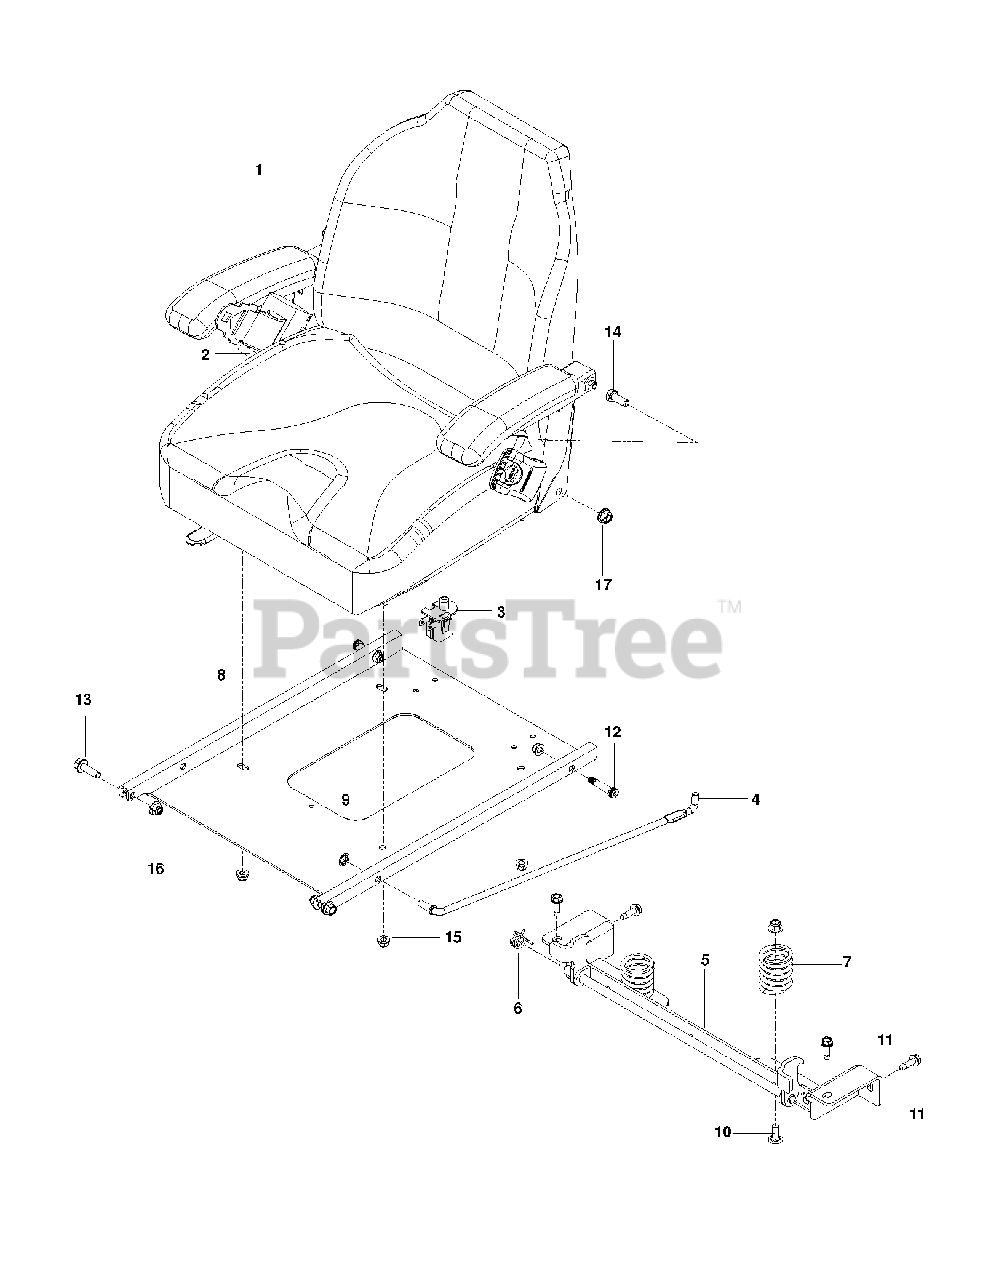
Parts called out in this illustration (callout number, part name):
1	SEAT.907.VINYL.HUSQVARNA
2	BELT, SEAT
3	SEAT SWITCH
5	LATCH.SEAT.BLACK
6	SPRING, TORSION
7	SPRING, SEAT
8	PAN, SEAT, BLACK
9	NUT 3/8 PALNUT RTNG BLK PHOS
10	RHSNB 3/8C X 1
11	RP BLT 5/16-18 X 1 THRD FORM D
12	BOLT, SHOULDER 3/8 X 1.25
13	HHFS 3/8-16 X 1.25 GD 5
14	HCS 7/16-14 X 1 GR 5 ZD
15	5/16-18 NYLOC FLANGE NUT
16	NUT 3/8-16 HEX FLG NYLOC ZD
17	NUT 7/16-14 HEX WHIZ LK
